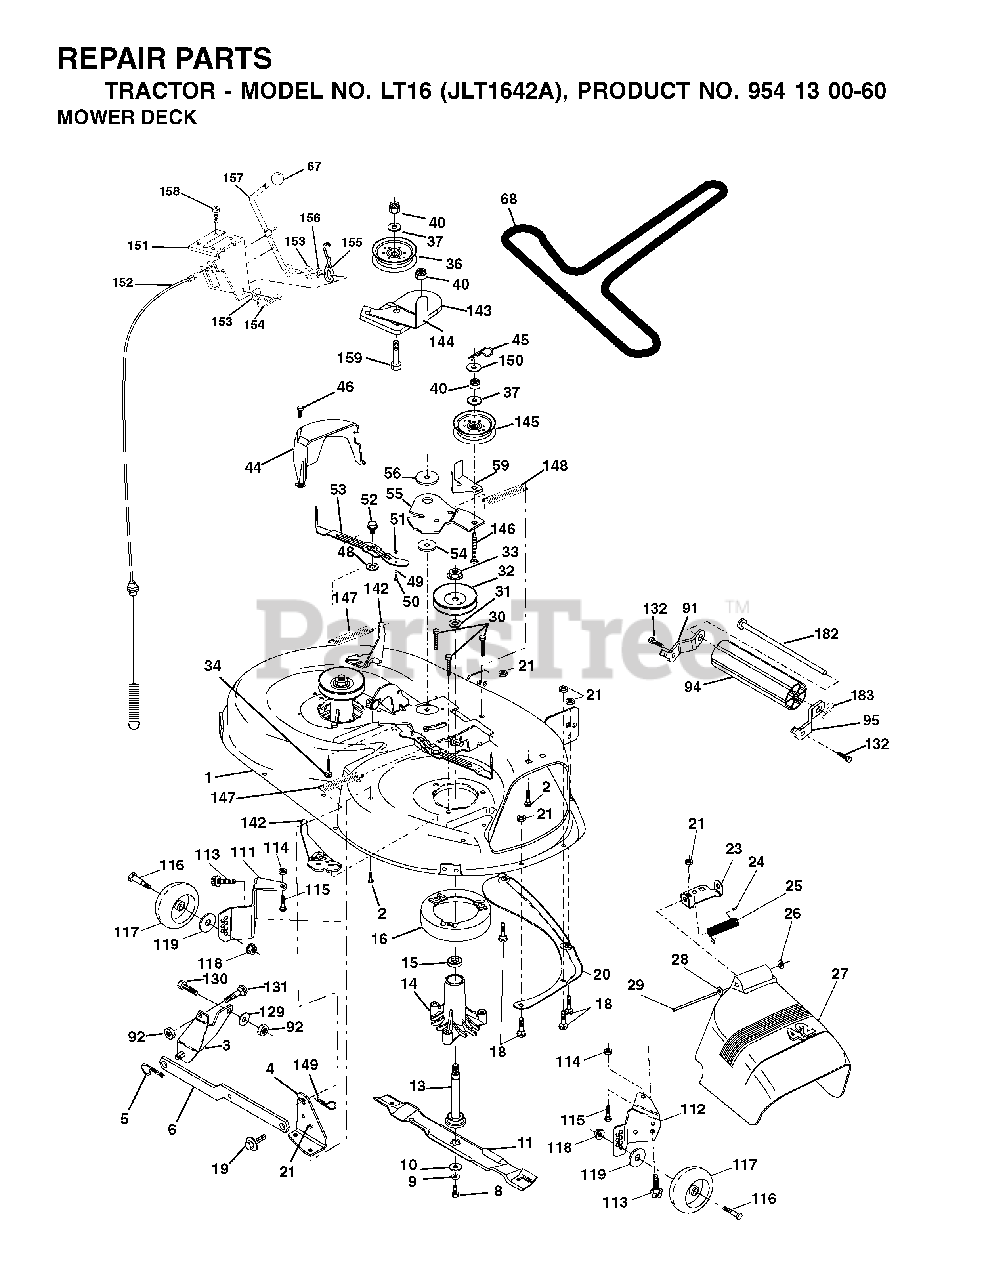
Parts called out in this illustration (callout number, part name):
1	42" DECK KIT
2	BOLT
3	BRKT ASM SWAY BAR
4	BRACKET SWAY BAR 42" DECK
5	RETAINER-SPRNG RB
6	BAR SWAY DECK
8	BLADE BOLT
9	LOCKWASHER
10	WASHER.BLADE
11	BLADE 42"
13	SHAFT ASM VENT
14	HSG MANDREL
16	STRIPPER, MWR ROUND
18	BOLT
19	BOLT SHD 5/16-18
20	BAFFLE.VORTEX
21	LOCKNUT
23	BRKT, DEFL. MOWER
24	CAP-SLEEVE LT
25	SPRING TORSION
26	NUT PUSH M
27	SHIELD DEFLECTOR
28	WASHER
29	ROD.HINGE
30	SCREW, WASHER HEAD
31	WASHER
32	PULLEY/MANDREL
33	NUT, FLG TOPLOCK 9/16"
34	BOLT
36	FLAT IDLER PULLEY
40	LOCKNUT
44	GUARD MANDREL LH BLACK
45	RETAINER M
46	SCREW.1/4-20X5/8
49	ROLLER ASM CAM FOLLOWER
50	BOLT
53	ARM
54	HARDENED WASHER
55	ARM IDLER 42" MOWER LT/YT
56	SPACER.RETAINER.MOWER
59	GUARD, BELT
67	KNOB T (3/8 HOLE)
91	BRACKET ASM NOSEROLLER LH
92	NUT
94	NOSE ROLLER
95	BRACKET ASM NOSEROLLER RH
111	BRACKET, WHEEL
112	BRACKET, WHEEL
113	SCREW.3/8-16X.625
114	NUT
115	BOLT
117	WHEEL.GAUGE.STANDARD
118	LOCKNUT
119	WASHER
129	WASHER
131	BOLT D
132	SCREW 3/8-16X3/4
142	ARM SPRING BRAKE MOWER
143	BRACKET, ARM IDLER
144	KEEPER.BELT.42".CLUTCH.CABLE
145	PULLEY
146	BOLT, CARRIAGE IDLER BLACK
148	IDLER RETURN SPRING
149	SPRING.RETAINER.YELLOW.ZINC
150	WASHER PM
151	BRACKET, CLUTCH CABLE
152	42" CLUTCH CABLE
153	WASHER FLAT 3/8"
154	SPRING RETAINER
155	SPRING RETENTION LEVER
156	SPACER CLUTCH CABLE
157	ROD CLUTCH CABLE 3/8"
158	SCREW
159	BOLT
182	ROD ROLLER NOSE STANDARD
183	SPRING RETAINER
